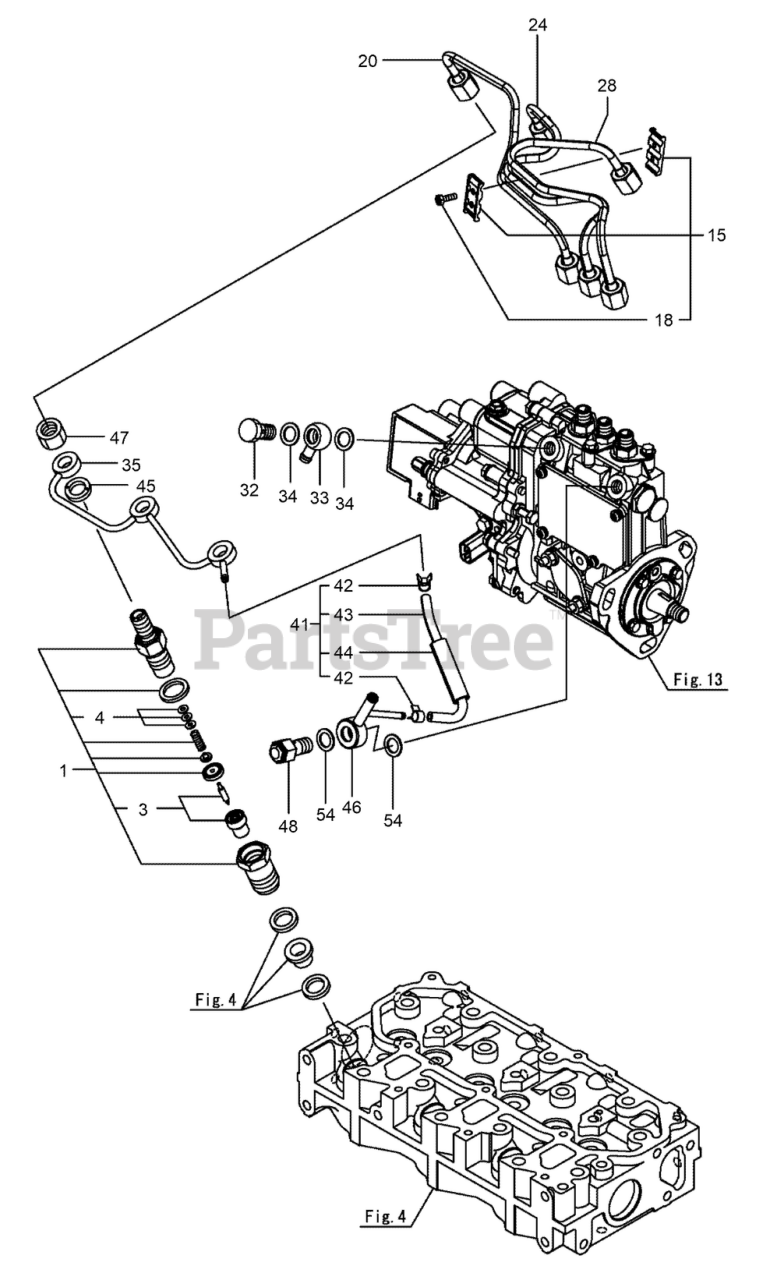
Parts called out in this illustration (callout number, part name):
1	NOZZLE ASM
3	NOZZLE ASM
4	SHIM SET-ADJUSTING
15	RETAINER-PIPE
20	PIPE ASM
24	PIPE ASM
28	PIPE ASM
32	BOLT-PIPE JOINT
33	JOINT-PIPE
34	WASHER-SEAL
35	PIPE ASM
41	PIPE ASSY, FO RETURN
42	CLAMP-HOSE
43	PIPE, FO RETURN
44	TUBE, CORRUGATED
45	GASKET
46	JOINT-OVER FLOW
47	NUT-NOZZLE
48	VALVE ASM-CHECK
54	WASHER-SEAL
